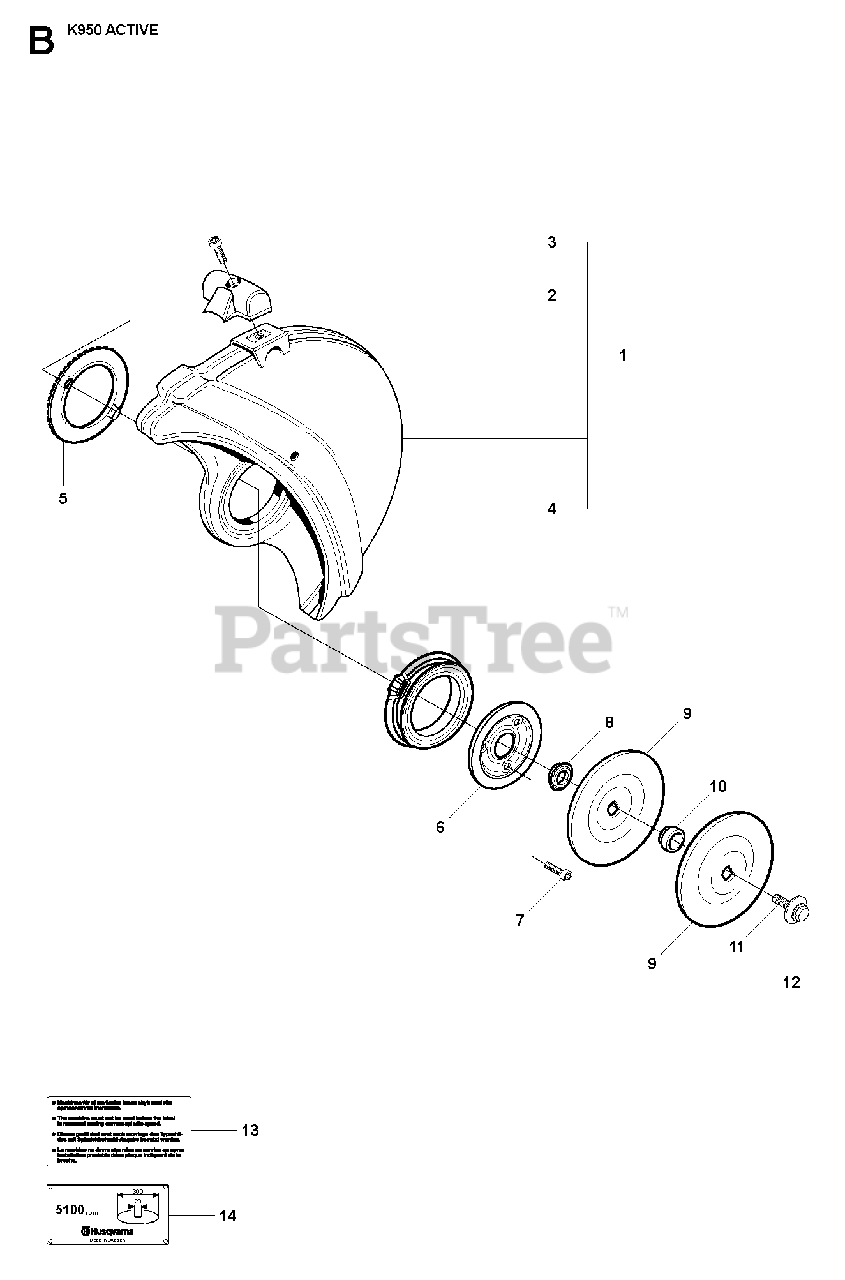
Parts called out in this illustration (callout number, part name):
1	WHEEL GUARD"12"". Incl. 2, 3, 4"
1	WHEEL GUARD"14"". Incl. 2, 3, 4"
1	GUARD"16"". Incl. 2, 3, 4"
3	SCREW IHSCM
8	SUPPORT FLANGE
9	FLANGE WASHERDiam. 105
9	FLANGE WASHERDiam. 119
10	BUSHINGDiam. 30,5
10	KITDiam. 22,2
10	KITDiam. 25,4
14	LABEL"12"", Diam. 20 mm"
14	LABEL"12"", Diam. 25,4 mm"
14	LABEL"14"", Diam 20 mm"
14	LABEL"14"", Diam. 25,4 mm"
14	LABEL"16"", Diam. 20 mm"
14	LABEL"16"", Diam. 25,4 mm"
